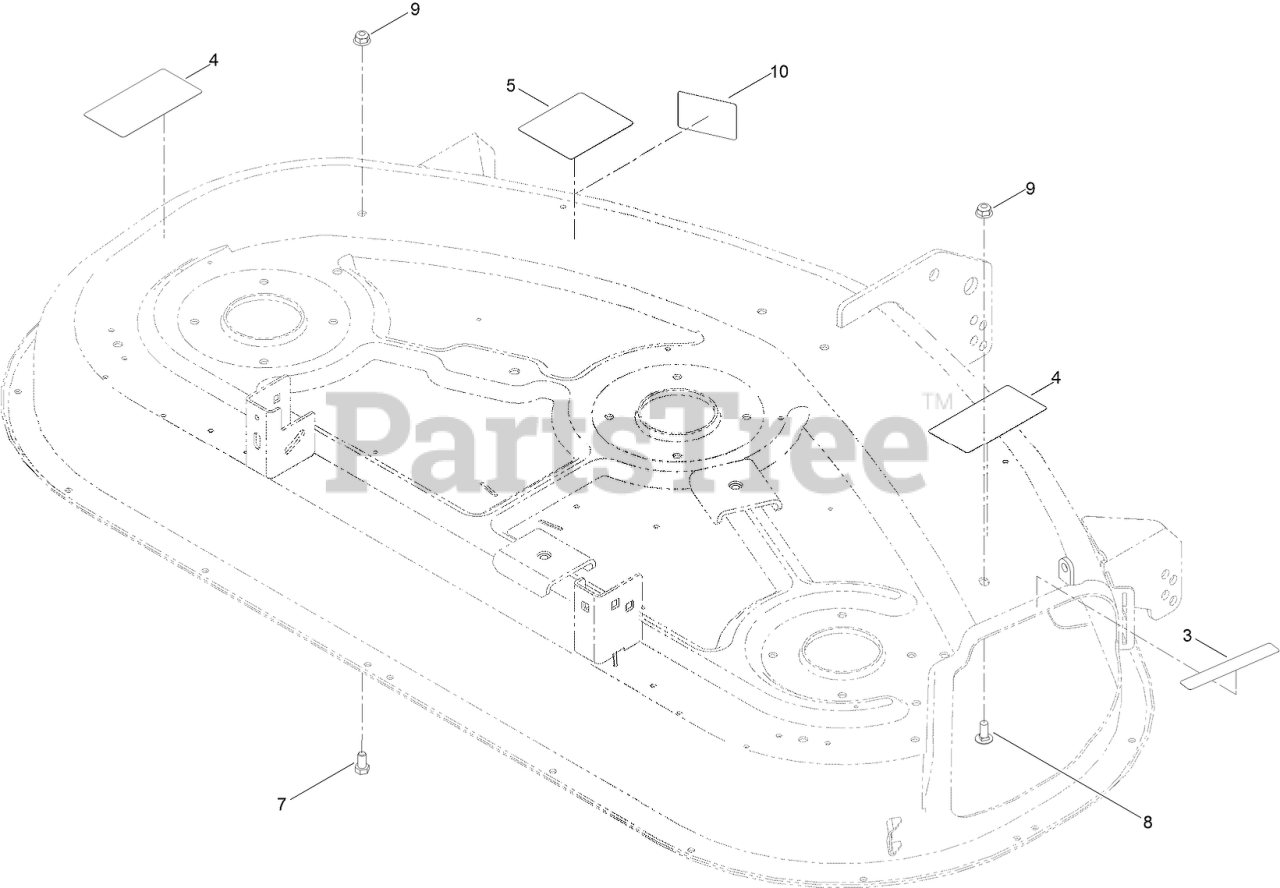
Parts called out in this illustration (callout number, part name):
3	DECAL-DANGER
4	DECAL-DANGER, DECK
5	DECAL-ROUTING, BELT
7	SCREW-HH
8	SCREW-CARR
9	NUT-HF, NI
10	DECAL-SCALP, ANTI
